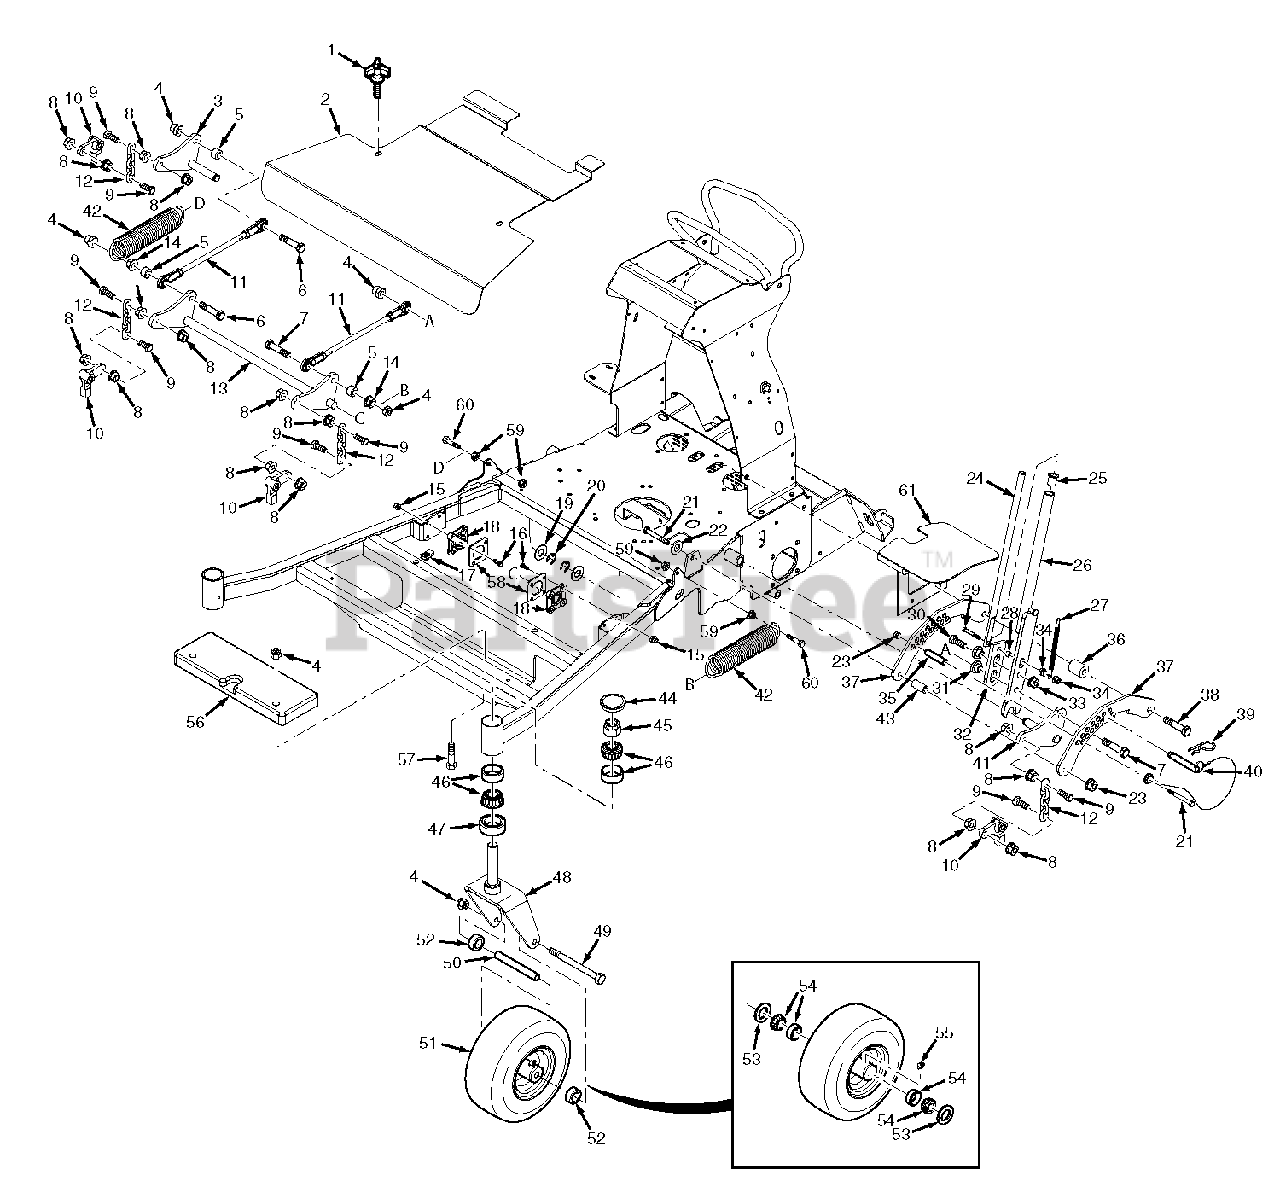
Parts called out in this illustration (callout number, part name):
1	Knob w/Stud
2	Belt Cover w/Decals
3	Arm Weldment, RH
4	Nut, Elastic Stop 1/2-13
5	Spacer
6	Bolt, Hex Head 1/2-13 x 2-1/2"
7	Bolt, Hex Head 1/2-13 x 3"
8	Nut, Serrated Flange 3/8-16
9	Bolt, Hex Head 3/8-16 x 1-1/2"
10	Lever, Deck Level
11	Linkage, Deck Lift
12	Chain
13	Deck Lift Weldment
14	Nut, Serrated Flange 1/2-13
15	Nut, Elastic Stop 5/16-18
16	Bolt, Hex Head 5/16-18 x 1"
17	U-Nut, 3/8-16
18	Bearing, Deck Lift - 61V
19	Flatwasher, 3/4-.766 x 1.25 x .0598
20	Retaining Ring, .750 "E"
21	Bolt, Hex Head 3/8-16 x 3"
22	Flatwasher, 3/8-.391 x .938 x .105
23	Nut, Elastic Stop 3/8-16
24	Actuator Rod
25	Bearing
26	Handle Weldment, Deck Latch
27	Spring, Deck Latch
28	Spacer
29	Bolt, Hex Head 3/8-16 x 2-1/2"
30	Bolt, Hex Head 1/2-13 x 1-3/4"
31	Bushing, Deck Latch
32	Deck Latch, Outer
33	Nut, Serrated Flange 1/2-13
34	Nut, Elastic Stop 3/8-16
35	Spacer
36	Spacer
37	Bracket, Deck Height
38	Bolt, Hex Head 1/2-13 x 4-1/2"
39	Hair Pin Cotter
40	Pin Assembly w/Lanyard
41	Arm Weldment, LH
42	Spring, Deck Lift
43	Spacer
44	Cap, Grease
45	Nut, Elastic Stop 1"-14
46	Bearing w/Race
47	Seal, 2" OD x 1.625 ID
48	Caster Yoke Weldment
49	Bolt, Hex Head 1/2-13 x 9-1/2"
50	Sleeve, Caster Wheel
51	Caster Wheel Assembly, 13 x 6.5
52	Seal
53	Roller Bearing, Short
54	Bearing w/Race
55	Grease Fitting
56	Weight
57	Bolt, Hex Head 1/2-13 x 2-3/4"
58	Reinforcement, Bearing
59	Nut, 3/8-16 Serrated Flange
60	Bolt, Hex Head 3/8-16 x 1-1/2" Grade 8
61	Fender Weldment
